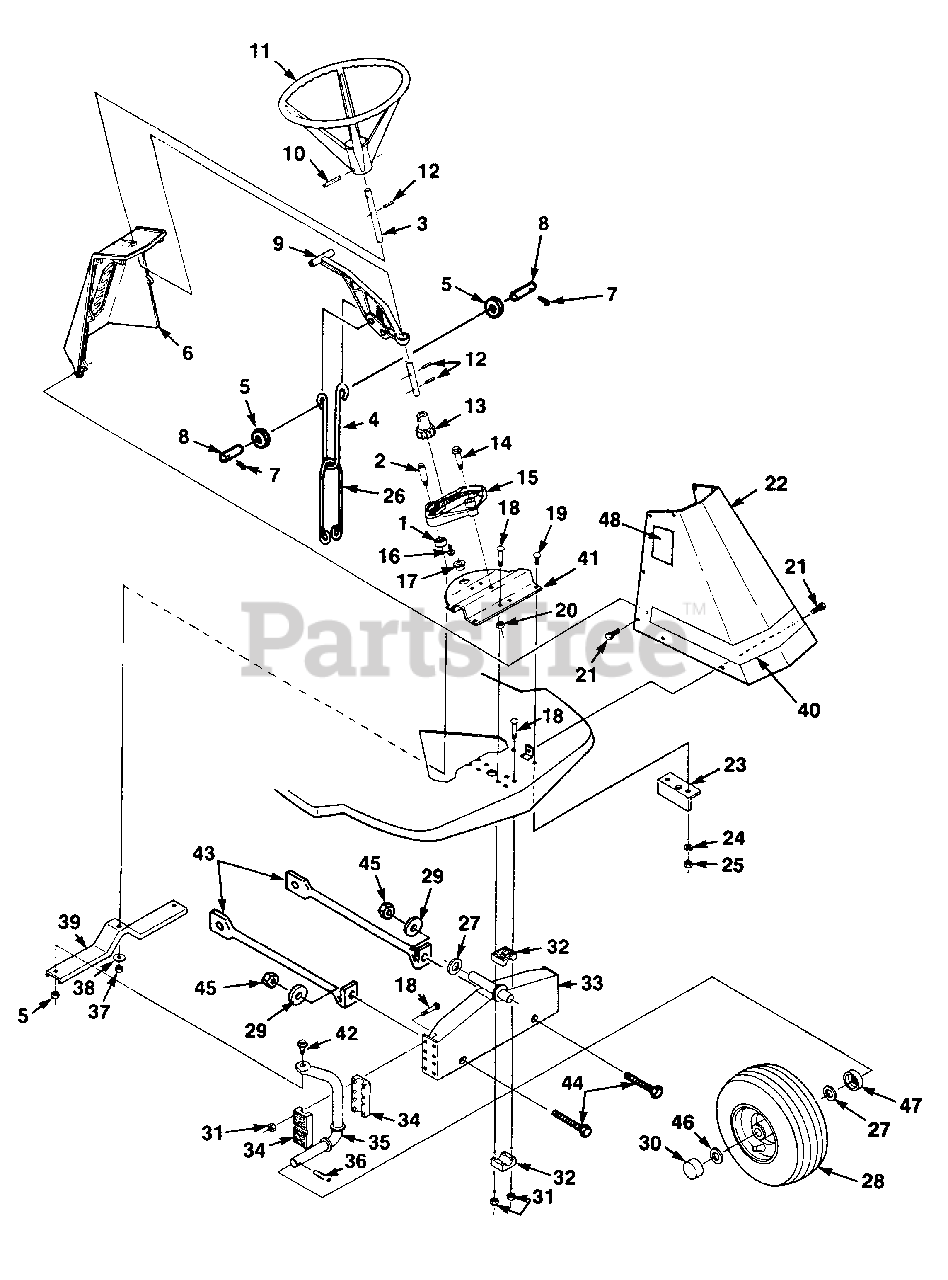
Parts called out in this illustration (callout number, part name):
1	BUSHING- Ball
2	STUD- Steer
4	LINK- Lift
5	WASHER- Flat 1/2"
6	PANEL- Console
7	PIN- Cotter
8	PIN- Retainer
9	HANDLE- Lift
11	WHEEL- Steering
13	PINION- Steering
14	BOLT- Shoulder 3/8-16 x .1 25
15	SECTION- Steering
16	SCREW 1/4-20 x 1/2
18	BOLT- 1/4-20 x 1 3/4 carr.
19	BOLT- 114-20 x 3/4 Carr. Sq. Nk.
20	NUT- 3/8-16 C'lock
21	BOLT- 1/4-14 x.44 Swedge form
22	SUPPORT- Steering
24	WASHER- Lock 114
25	NUT- 1/4-20 hex
26	LINK- Lower lift
27	WASHER- Flat 3/16
28	WHEEL & TIRE
29	WASHER- Plain (Flat 13/32)
31	NUT- 1/4-20 hex C'lock
33	AXLE- Front
35	SPINDLE- L.H. Wheel
36	PIN
37	NUT- C'Locking-hex 3/8-24
38	WASHER- Flat 3/8
39	BRACKET- Steering
40	DECAL- Product Identification
41	BRACKET- Reinforcement
43	SUPPORT- Frame axle
44	BOLT- 3/8-16 x 5/8
45	NUT 3/8-16 C'Lock
47	WASHER- Dust
48	DECAL- (8 H.P.)
